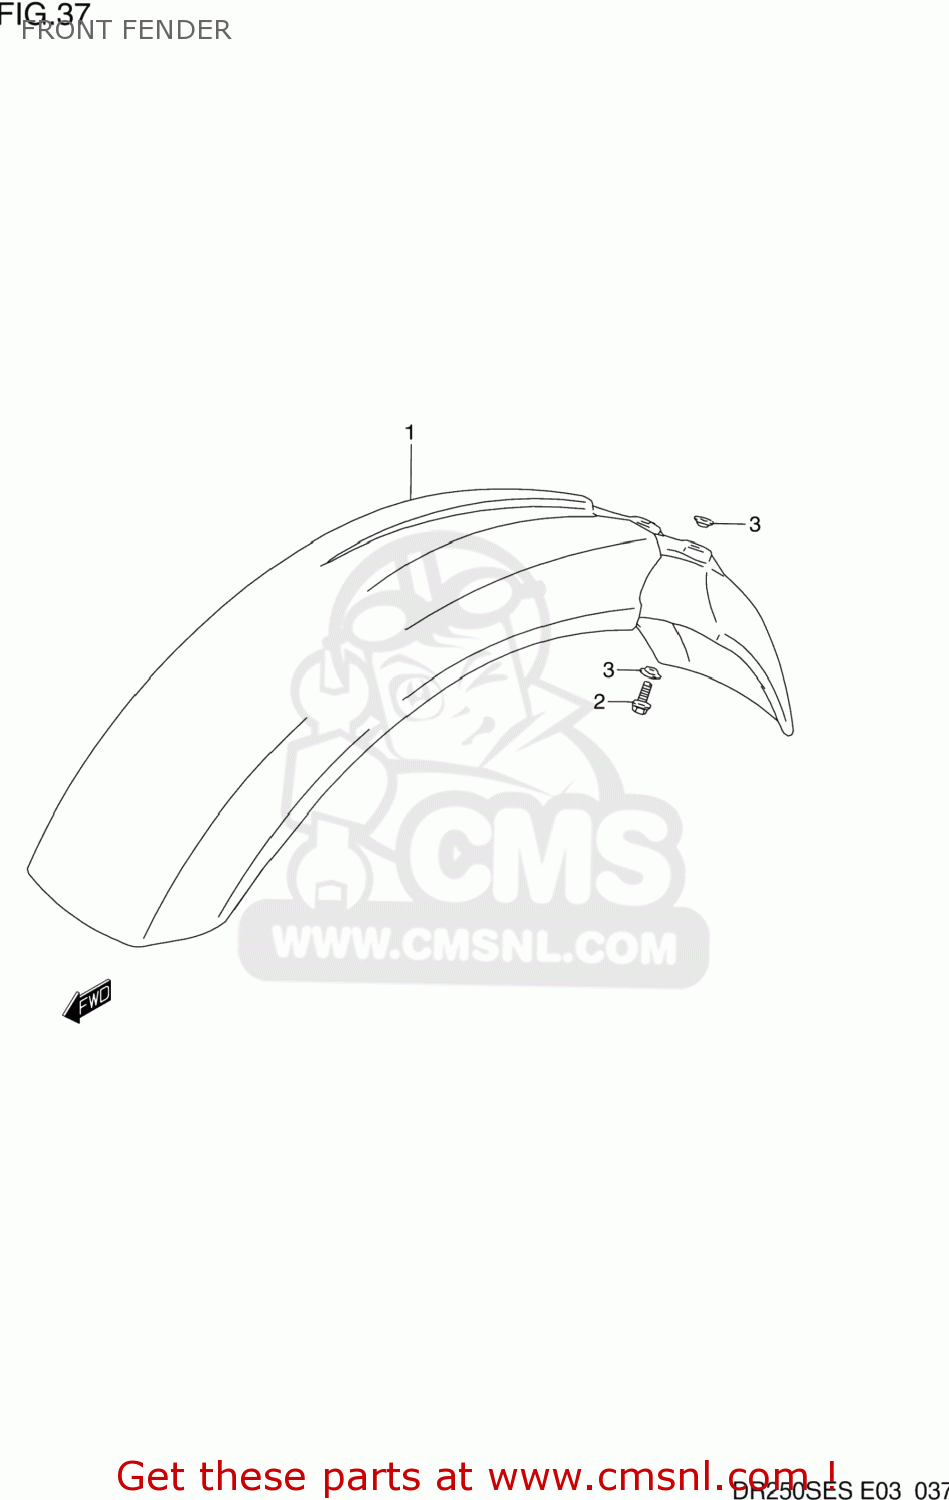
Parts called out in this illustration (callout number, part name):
1	FENDER,FR
2	BOLT
3	WASHER
